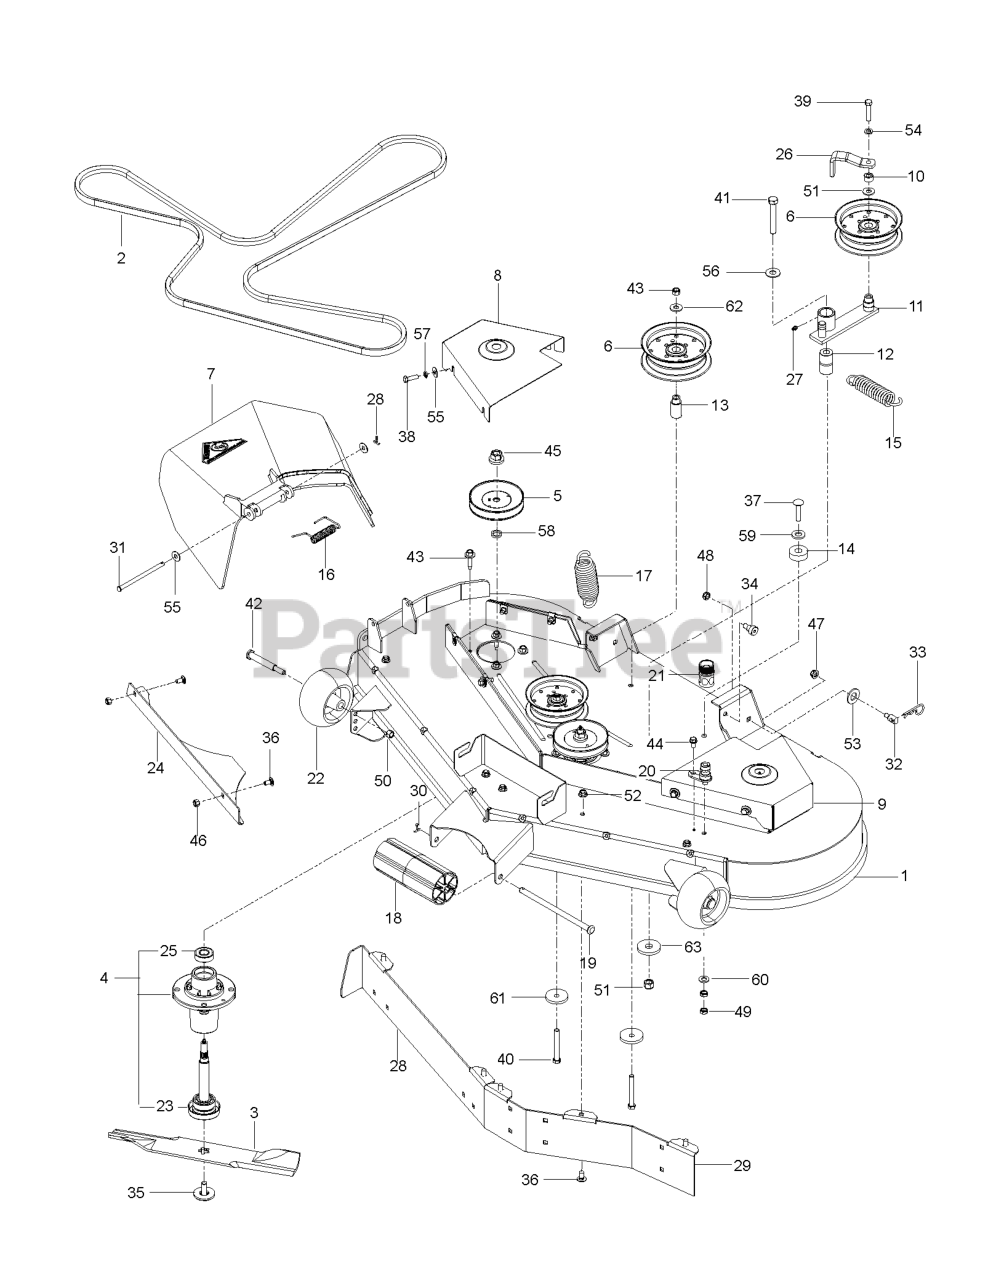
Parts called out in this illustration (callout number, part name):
1	DECKS
2	BELT, DECK
3	BLADE, 16-1/4"
4	MANDREL ASM, CAST IRON
5	PULLEY MANDREL
6	PULLEY, IDLER
7	DISCHARGE CHUTE 48"
8	BELT SHIELD - R.H. ORANGE
9	BELT SHIELD - L.H. ORANGE
12	PIVOT BUSHING
13	IDLER BUSHING
14	ISO-MOUNT BUSHING
16	SPRING - TORSION
18	NOSE ROLLER 48"
19	ROD.ROLLER.NOSE.NARROW.48"
20	PORT.WASHOUT
21	COUPLING.QUICK CONNECT
22	WHEEL GAGE DONUT
23	SHAFT ASM MANDREL
24	CONFINEMENT PLATE 48" BLK
26	GUIDE, BELT
27	ZERK
28	KIT.BOLT.BAFFLES.FRONT.48".ORN
29	KIT.BOLT.BAFFLES.FRONT.48".ORN
30	COTTER PIN
31	PIN-CLEVIS 5/16 DIA X 5.19 ZD
32	STUD.FASTNER.W/ANTI-ROTATE
33	HAIRPIN #4
34	SB 3/8-16 X 3/8 SKT HD ZD
35	BOLT.WASHER.ASM.7/16-2
36	BOLT.CARR.5/16-18X5/8.SHORT
37	RHSNB 3/8-16X1-3/4
38	BOLT.FIN.HEX.5/16-18UNC X 1.00
39	BOLT
40	BOLT.HEX.FIN.3/8-16 X 3.GR5
41	HCS 1/2-13 X 3-1/4 GD 5 ZD
42	BOLT.SHOULDER.3/8-16X3-5/8.
43	BOLT.HEX.WASHR.HED.313-18X1.19
44	SCREW
45	NUT.FLANGE.LOCK.TOP
46	NUT.71038.31-18.HEX.NYLOCK
47	5/16-18 NYLOC FLANGE NUT
48	NUT HEX 3/8-16 NYLON, THIN
49	NUT
50	NUT 3/8-16 NYLOC
51	NUT.LK.W/WSH.1/2.
52	NUT 5/16C WHIZ
53	WASHER
54	LOCKWASHER
55	WASHER.5/16.FLAT.STE.STD.
56	WASHER 1/2 FLAT
57	WASH.5/16.SLW.ZD
58	WASHER.SPACER.MANDREL
59	WASHER STEEL
60	WASHER
61	SPINDLE WASHER
62	RP WASHER 3/8 FLAT
63	HEAVY WASHER
